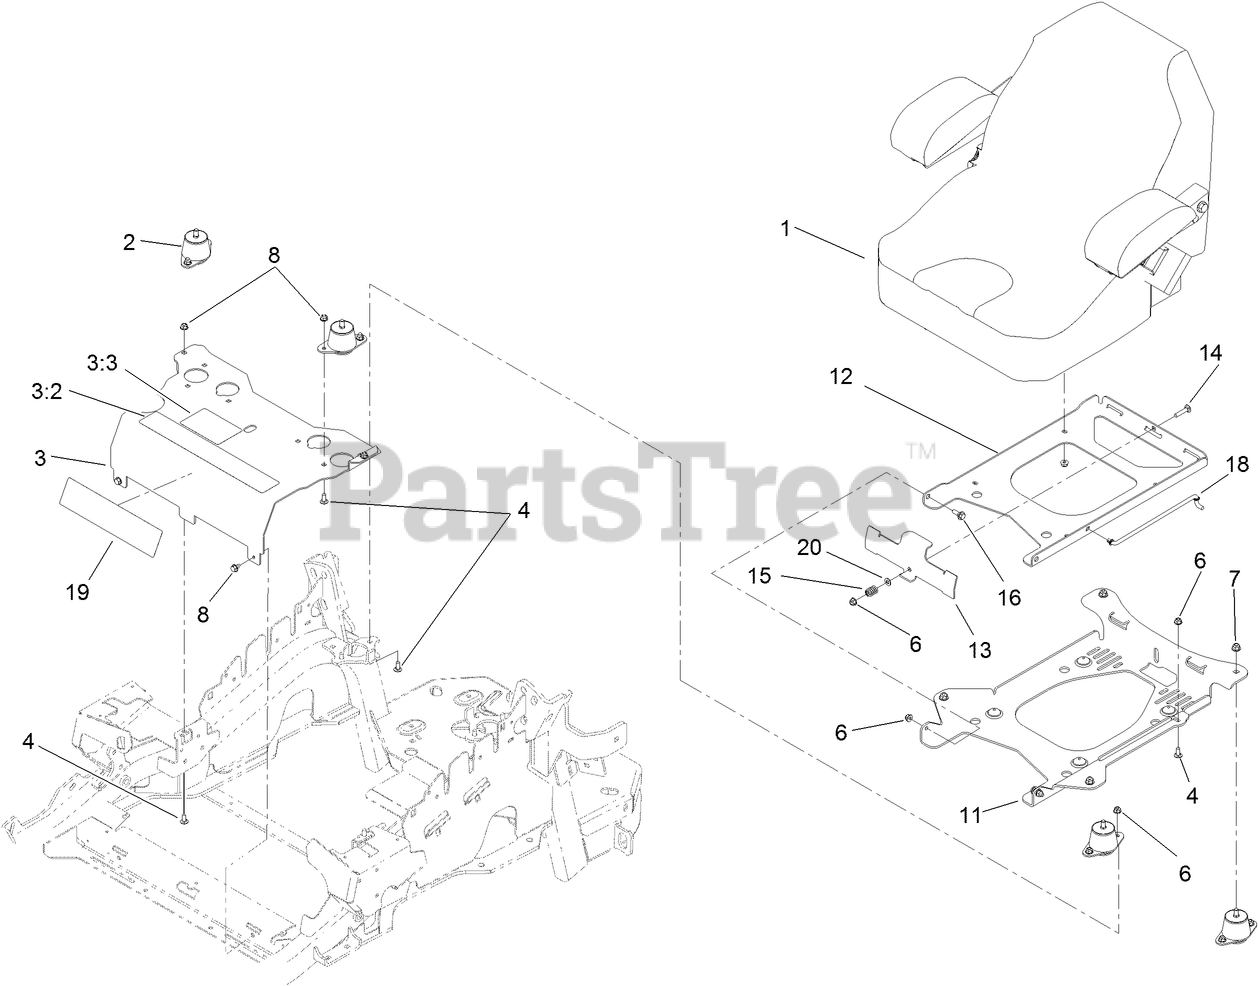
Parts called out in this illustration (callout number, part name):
1	SEAT-STANDARD
2	ISOLATOR-SEAT
3	MOUNT-SEAT
3:2	DECAL-CONSOLE
3:3	DECAL-SERVICE AID
4	SCREW-CARR
6	NUT-HF, NI
7	NUT-HF, NI
8	SCREW
11	PLATE-TILT, SEAT SUPPORT
12	PLATE-FRAME, SEAT
13	PLATE-LATCH, SEAT
14	BOLT-CARR
15	SPRING-COMPRESSION
16	SCREW-SHOULDER
18	ROD-PROP
20	WASHER-PLAIN
